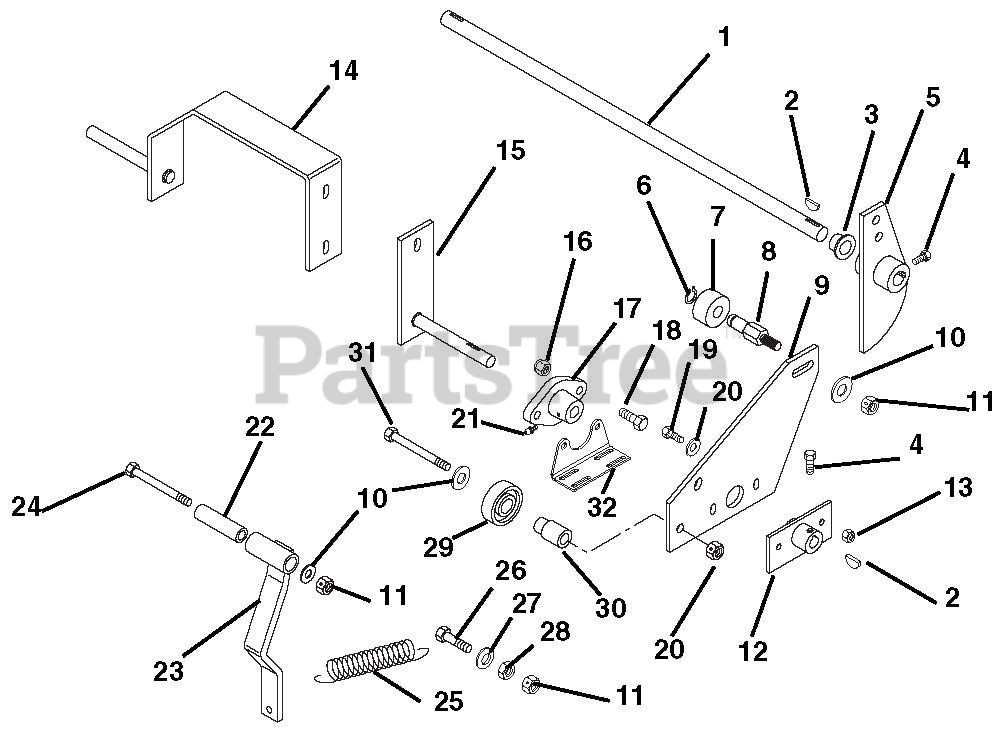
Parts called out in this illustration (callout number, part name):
1	SHFT,SPEED CTL CAM
2	KEY-WDRF .125X.75
3	BSHG-FLG .630X1.000X.625 NY
4	@BLT-HEX .25-20X.50 GR5 YWZC
5	WLDMT,CONTROL CAM
6	RG-RTNG-EXT.50 X .034
7	Roller-Nylon
8	PIN,ROLLER
9	ARM,SPEED CONTROL
10	@WSHR-FL-STL.406X.812X.065 YWZ
11	@NUT-LK-CTR .38-16 YWZC
12	ARM, SPEED CONTROL
13	@NUT-LK-CTR .25-20 YWZC
14	WLDMT,PUMP CONTROL R.H.
15	WLDMT,PUMP CONTROL L.H.
16	@NUT-LK-CTR .31-18 YWZC
17	BUSHING, FLANGED
18	@BLT-HEX .31-18X1.00 GR5 YWZC
19	@BLT-HEX .25-20X.75 GR5 YWZC
20	@WSHR-FL-STL.281X.62X.065 YWZC
21	FTG,LUBE, .25-28 SELF THREAD
22	BUSH.,S.385X.610X1.80 ST
23	WLDMT, DETENT STRAP
24	@BLT-HEX .38-16X3.25 GR5 YWZC
24	@BLT-HEX .38-16X2.75 GR5 YWZC
25	SG-TENS .063X.62X2.75
26	@BLT-HEX .38-16X1.50 GR5 YWZC
27	@WSHR-LK .38X.094 REG YWZC
28	@NUT-HEX .38-16 YWZC
29	BRG-BALL .500X1.38X.437
30	HUB, BRG. MOUNT
31	@BLT-HEX .38-16X2.00 GR5 YWZC
32	BRACKET, STEERING SWITCH
